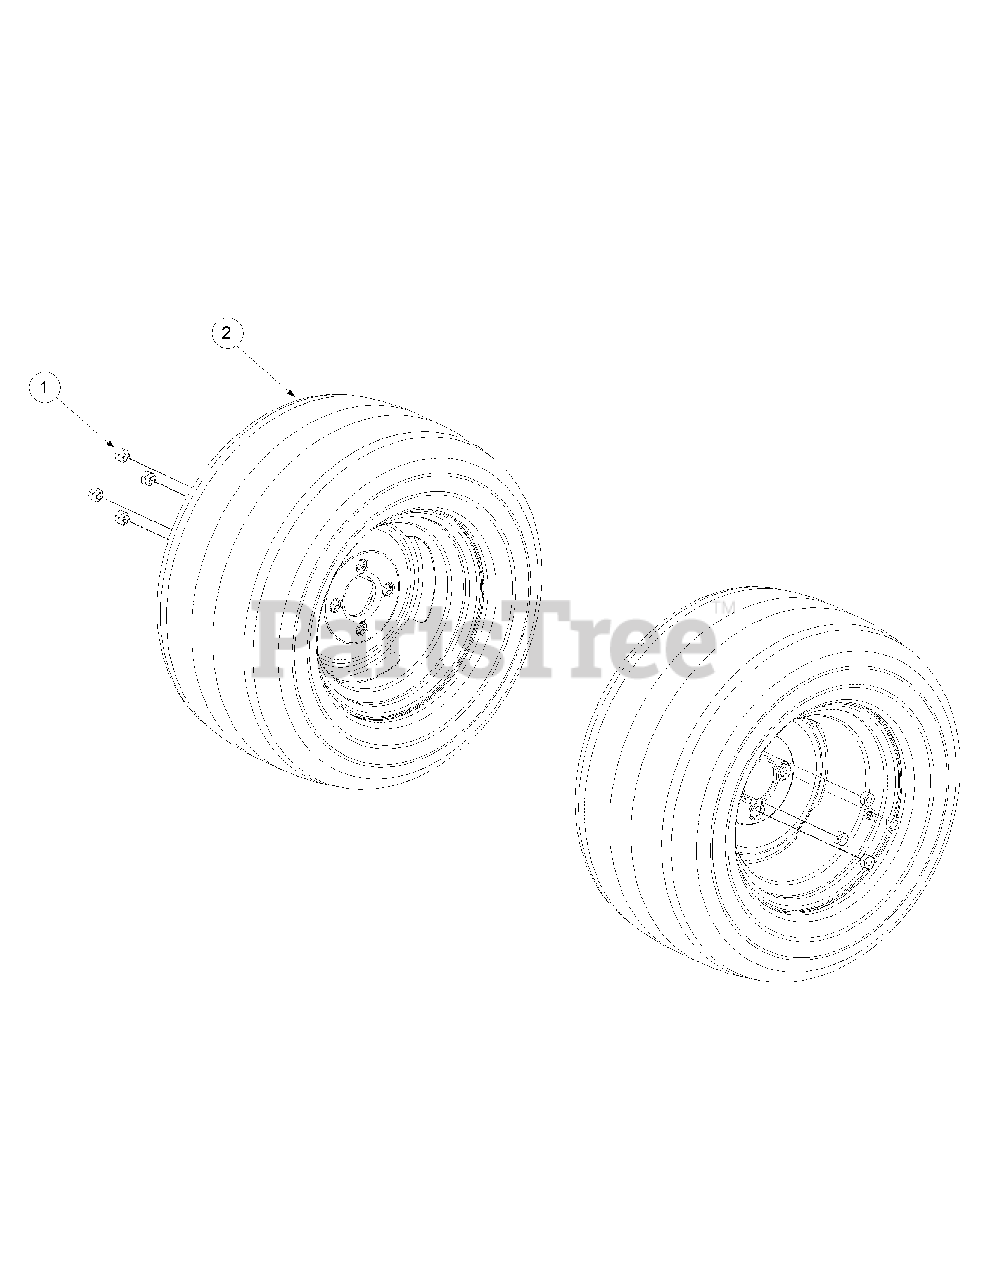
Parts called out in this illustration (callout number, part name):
1	Lug Nut, 1/2-20
2	Wheel Assembly, 24 x 12.00-12, Beige
2	Tire, 24 x 12.00-12
2	Rim, 12 Dia x 8.50 width
2	Wheel Assembly, 24 x 12.00-12, Turf Saver
2	Tire, 24 x 12.00-12, Turf Saver
